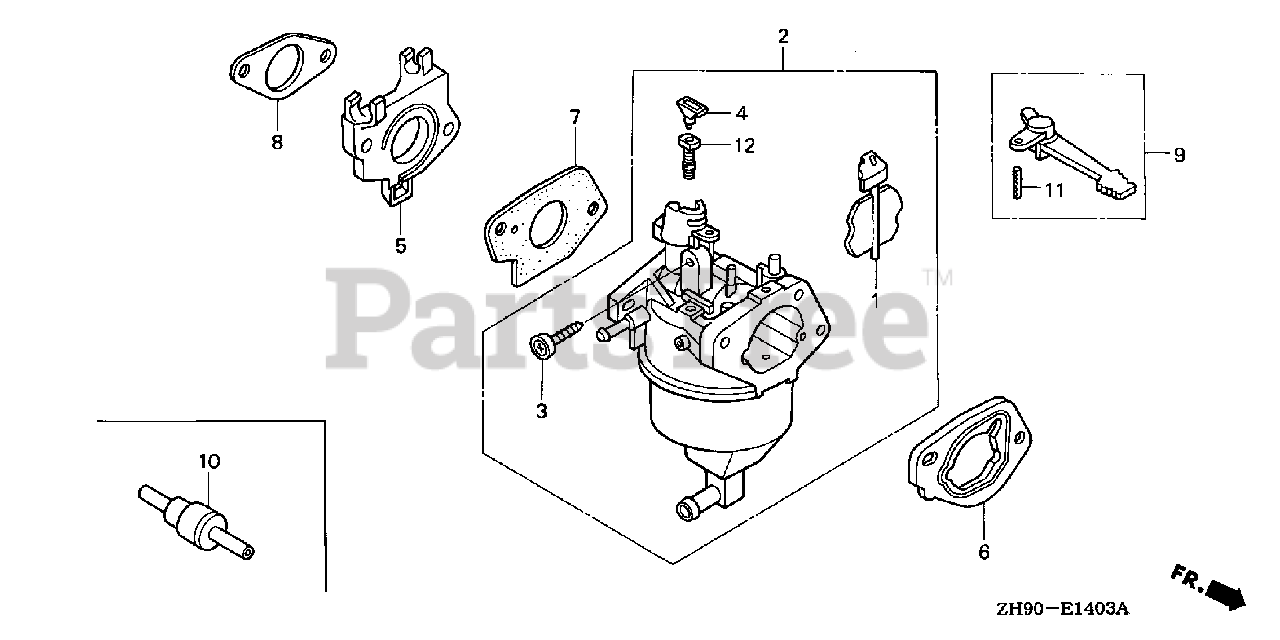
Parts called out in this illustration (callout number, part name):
1	CHOKE SET
2	CARBURETOR ASSY. (BEL3A A)
3	SCREW, THROTTLE STOP
4	COLLAR, SET
5	INSULATOR, CARBURETOR
6	SPACER, CARBURETOR
7	GASKET, CARBURETOR
8	GASKET, INSULATOR
9	LEVER, CHOKE (STD)
10	VALVE, DASHPOT CHECK
11	PIN, SPRING (2X12)
12	JET, PILOT (#45)
